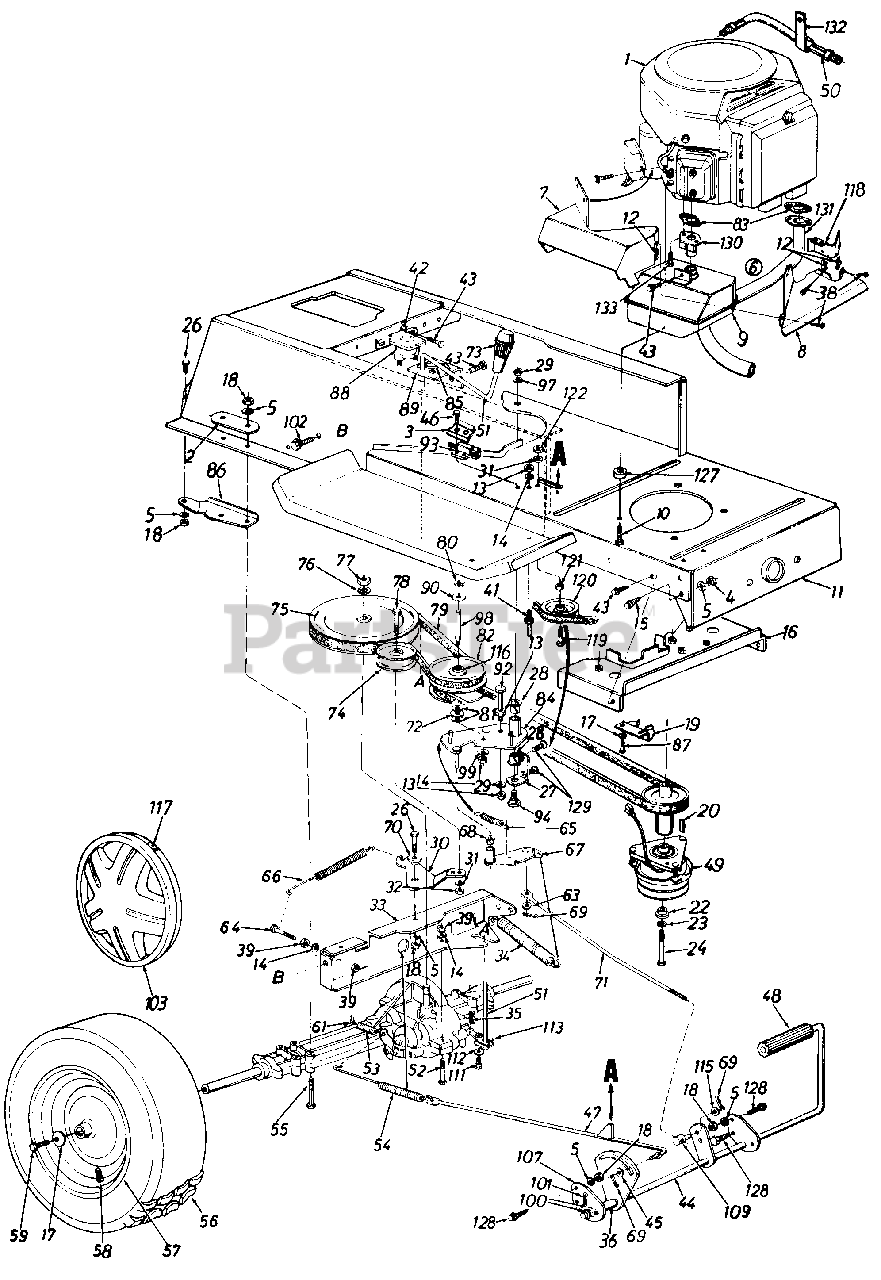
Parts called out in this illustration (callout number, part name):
1	Engine
3	Switch Plate
4	Hex Nut 5/16-24 Thd.
5	L-Wash. 5/16" I.D.
6	Muffler Ass'y. Comp.
7	Muffler Heat Shield
8	Front Heat Shield
9	Muffler Sub Ass'y.
10	Hex Wash Hd. AB-Tap Scr. 3/8-16 Thd.
11	Lower Frame Ass'y.
12	Speed Nut #10-24 Thd.
13	Hex Nut 1/4-20 Thd.
14	L-Wash. 1/4" I.D.
15	Hex TT-Tap Scr. 5/16-18 x .62"
16	Belt Guard Brkt. Ass'y.
17	Bell-Wash. .345" I.D. x .88"
18	Hex Nut 5/16-18 Thd.
22	Shld. Spacer.445" I.D.
23	L-Wash. 7/16" I.D.
24	Hex Bolt 7/16-20 x .5" Lg.
26	Hex Bolt 5/16-18 x .75" Lg.
27	Bearing Shaft Bracket Ass'y.
28	Flanged Nyliner Brg. 5/8" I.D. x .88" Lg.
29	Hex Nut 3/8-24 Thd.
31	L-Wash. 3/8" I.D.
32	Hex Nut 3/8-24 Thd.
33	Transaxle Support Brkt.
34	Ext. Spring .94" O.D. x 7.58"
35	Inter. Cotter Pin
36	Spacer.63" I.D.
38	Hex AB-Tap Scr. #10 x .5" Lg.
39	Hex Nut 1/4-28 Thd.
41	Belt Guard Pin
42	Ext. L-Wash. 1/4" I.D.
43	Hex Wash. Hd. S-Tap Scr. 1/4-20 x .50" Lg.
44	Clutch/Brake Pedal Ass'y.
45	Fl-Wash.
46	Truss Mach. Scr. B-Tap Scr. #10 x .5" Lg.
47	Brake Rod Ass'y.
48	Foot Pad
49	Electric Clutch
50	Hydraulic Hose 13" Lg.
51	Shift Lever Ass'y.
52	Hex Bolt 1/4-28 x 1.75" Lg.
53	Ext. Spring .38" O.D. x 2.5"
54	Ext. Spring .59" O.D. x 7.08"
55	Hex Bolt 5/16-18 x 2.75"
57	Wheel Rim Only
58	Air Valve
59	Hex Bolt 5/16-24 x .75" Lg.
61	Brake Return Spring Anchor
63	Fl-Wash. .34" I.D. x .68" O.D.
64	Hex Bolt 1/4-28 x 1.25" Lg.
65	Ext. Spring
66	Ext. Spring .62" O.D. x 6.12"
68	Flanged Bearing
69	Cotter Pin 3/32" Dia.
70	Shoulder Spacer .27" Lg.
71	Speed Control Link
72	Truss Bearing .56 Dia. x 1.25"
73	Shift Knob
74	Fl-Idler Pulley 3.25" x .75"
75	'/2""V"-Pulley
76	L-Wash. 1/2" I.D.
77	Hex Jam Nut 1/2-20 Thd.
78	Hex Bolt 3/8-24 x 1.75" Lg.
79	Variable Speed Belt
80	Snap Ring .56" Dia.
81	Fl-Wash.
82	Variable Speed Pulley Ass'y. 5" O.D.
83	Gasket
88	Solenoid
90	Teflon Washer .565" I.D.
92	Hex Bolt 1/4-20 x 3.25" Lg.
93	Safety Switch (Clutch)
94	Shld. Bolt 3/8-24 x 3.12" Lg.
97	Bell-Wash. .38" I.D. x .88"
98	Shaft .56" Dia. x 3.875" Lg.
99	Bell-Wash. .39" I.D. x 1.12"
100	Fl-Wash. .64" I.D. x .94"
101	Cotter Pin 1/8" Dia. x 1.25"
102	Hex Wash. Hd. Scr. 5/16-18 x.62" Lg.
103	Hub Cap
109	Ferrule
111	Hex Bolt 1/4-28 x .50" Lg.
112	Bell-Wash. .265" I.D. x .75"
113	Shift Lever Link Ass'y.
115	Fl-Wash. .385" I.D. x .62"
116	Needle Brgs.
117	Spring Clip
118	Front Heat Shield Ext.
119	Hex Bolt 3/8-16 x 1.25" Lg.
120	Fl-Idler w/Flanges 2.75" O.C.
121	Fl-Wash. .39" I.D. x 1.12" O.D.
122	Hex Nut 3/8-16 Thd.
127	Spacer 5/16" I.D.
128	Hex Wash. TT-Tap Scr. 5/16-18 x.75" Lg.
129	Hex Wash. AB-Tap Scr. 5/16-18 x.75" Lg.
130	Inlet Tube Ass'y.
131	Formed Tube Ass'y.
132	Clamp
133	Hex Bolt w/Washer
